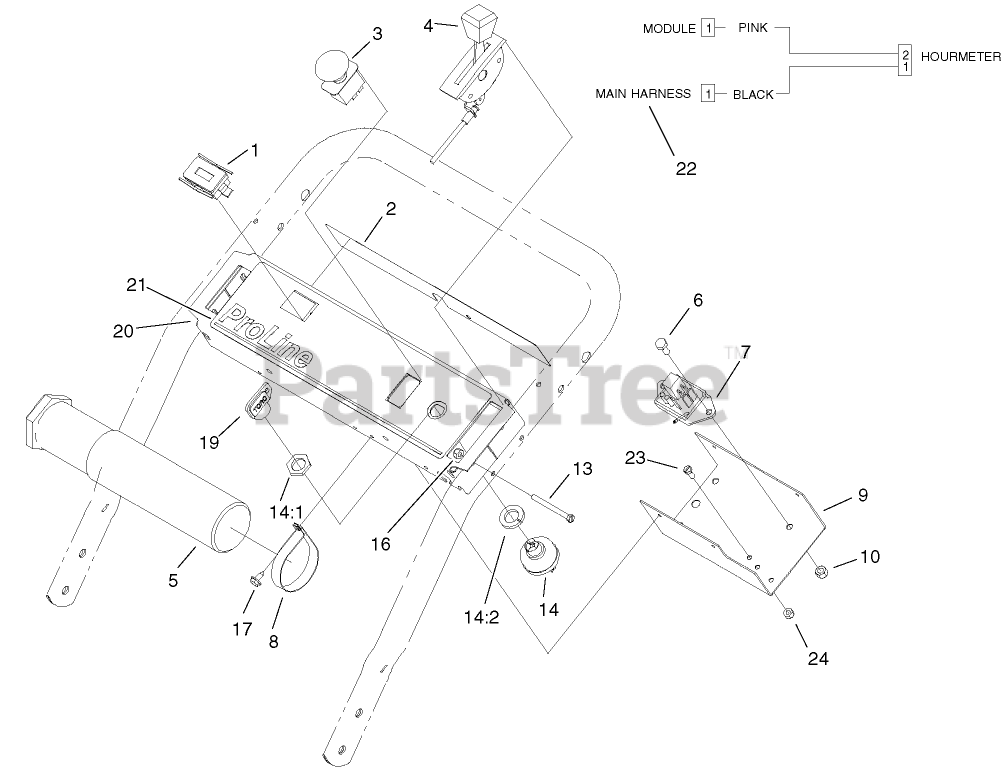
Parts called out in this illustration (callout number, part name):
1	HOURMETER
2	DECAL-WARNING
3	SWITCH-PTO
4	CONTROL-THROTTLE
5	TUBE-MANUAL
6	SCREW-HH
7	MODULE-DELAY
8	CLAMP-R
9	PANEL-BOTTOM
10	NUT-LOCK, NI
13	SCREW-SHH
14	SWITCH-ON / OFF
14:1	NUT-HH
14:2	WASHER-TOOTH, INTERNAL
16	NUT-LOCK, NI
17	SCREW-HWHTF
19	KEY-IGNITION
20	PANEL-CONTROL
21	DECAL-PANEL, CONTROL
23	SCREW-SHH
24	NUT-LOCK, NI
